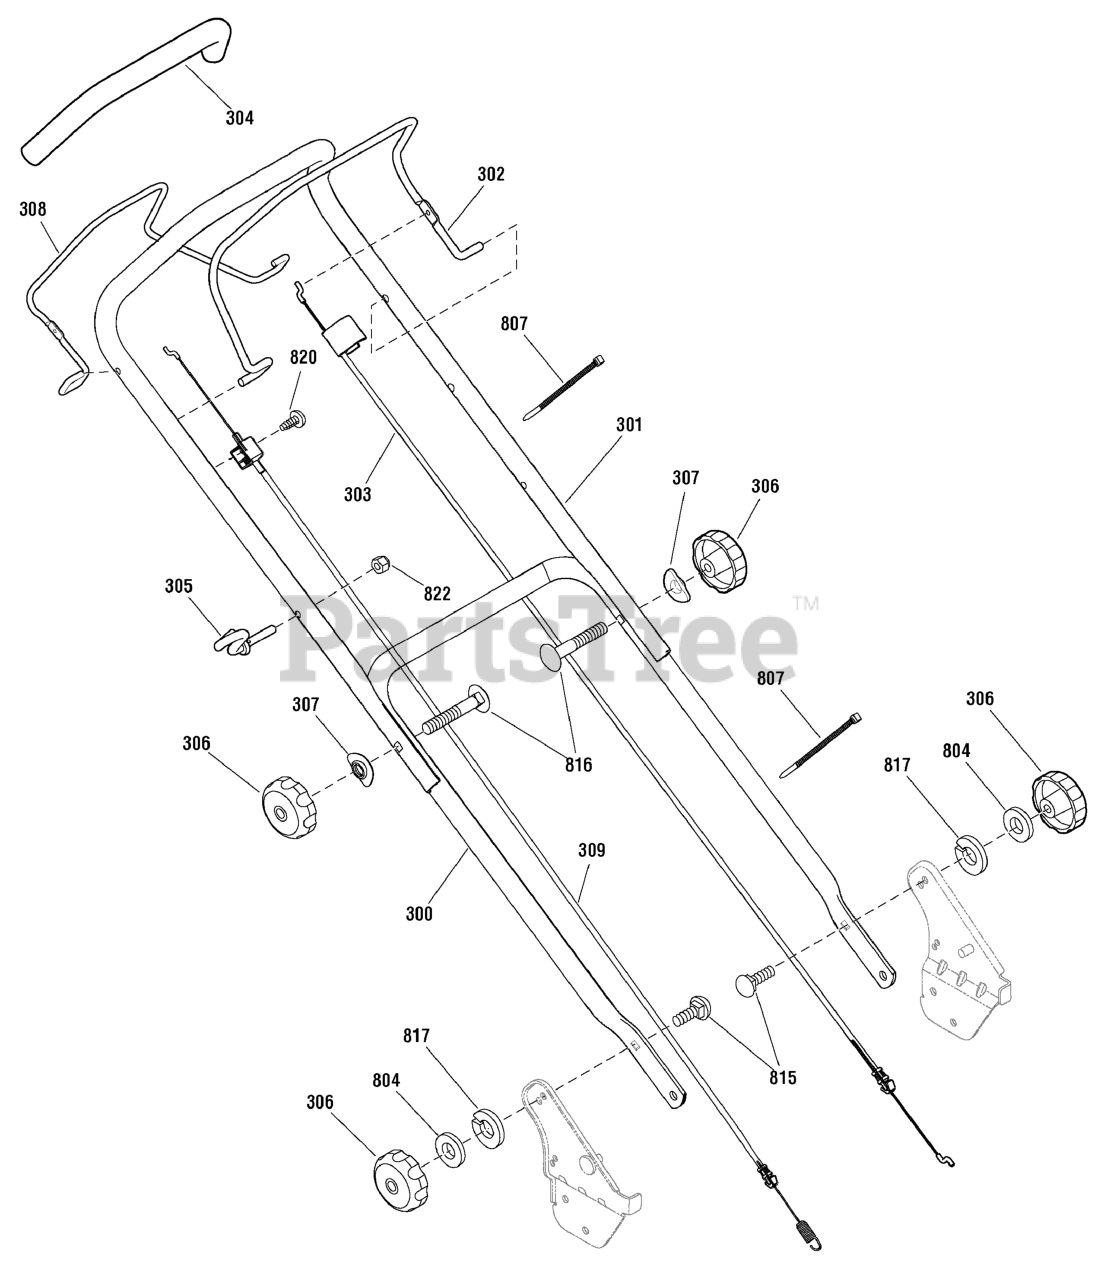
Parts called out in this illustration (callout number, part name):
300	HANDLE, Lower
301	HANDLE, Upper
302	LEVER, Engine Stop
303	CABLE, Engine Stop
304	TUBING, Foam
305	GUIDE, Rope, 1/4-20
306	KNOB, 5/16-18
307	WASHER, Formed
308	LEVER, Drive
309	CABLE ASSEMBLY, Drive
804	WASHER, 5/8
807	CABLE TIE
815	BOLT, Carriage, 5/16-18 x 1-1/8
816	BOLT, Carriage, 5/16-18 x 2
817	WASHER, Lock
820	SCREW, Tap, #10 x 1-1/4
822	NUT, Hex, 1/4-20
